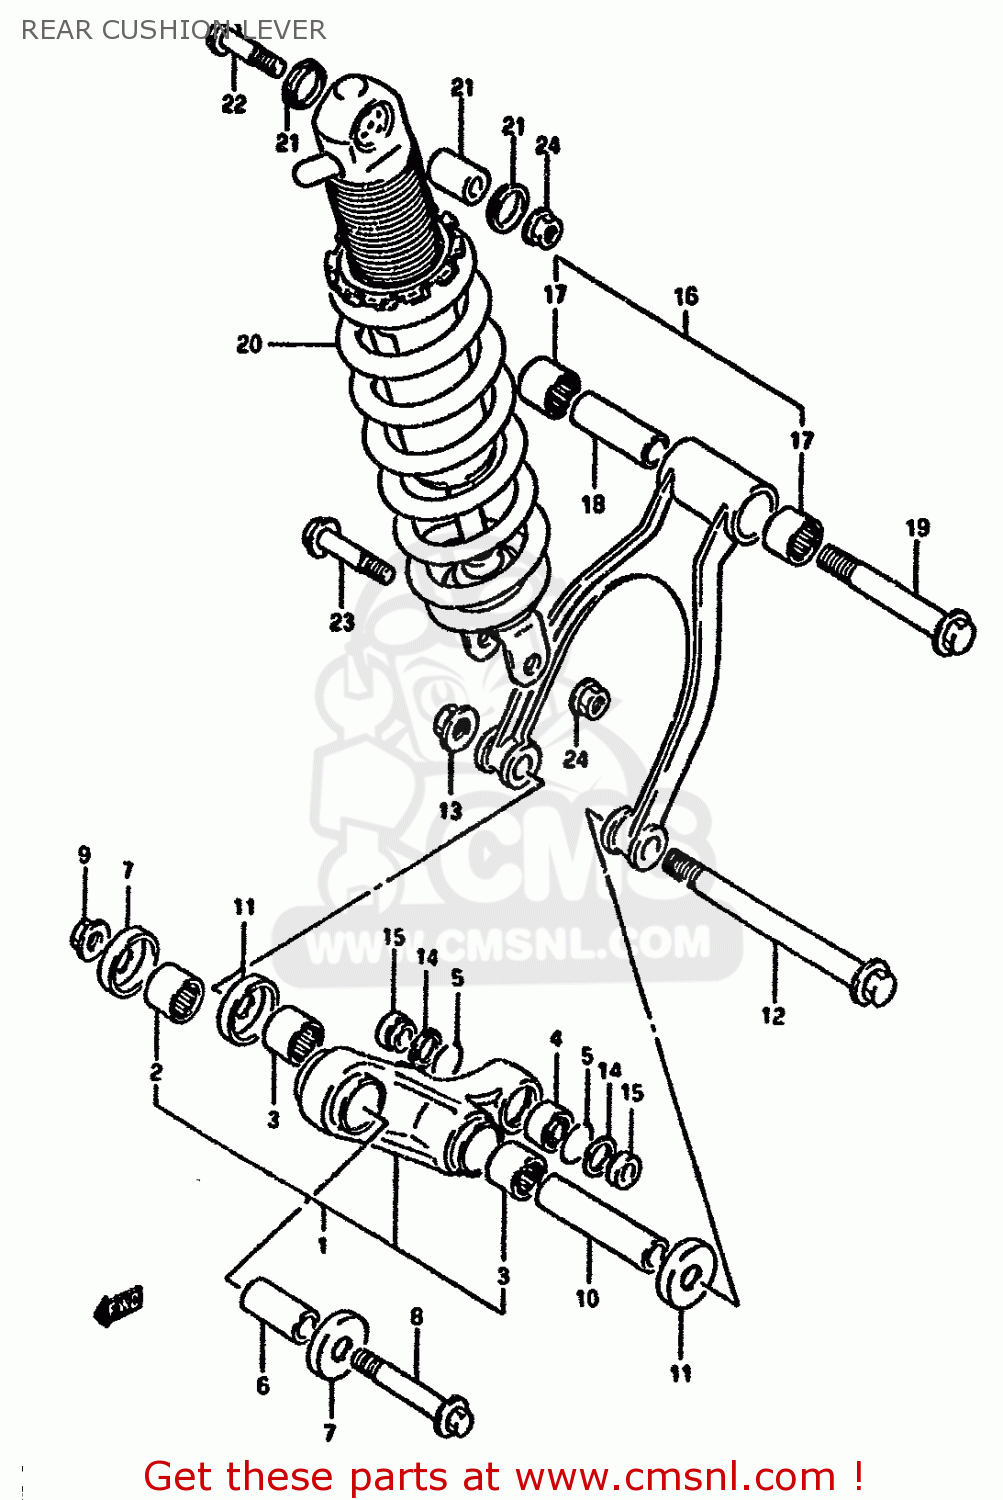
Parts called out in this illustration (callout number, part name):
1	LEVER SET,REAR CUSHION
2	BEARING(20X27X30)
3	BEARING(20X27X23.5)
4	BEARING,REAR SHOCK ABSORBER
5	RING,STOPPER
6	SPACER,RR CUSHION LEVER FR
7	SEAL,RR CUSHION LEVER FR DUST
8	BOLT,RR CUSHION LEVER FR
9	NUT 12MM
10	SPACER (14X20X78)
11	SEAL,RR CUSHION LEVER CTR DUST
12	BOLT,RR CUSHION ROD LWR
13	NUT
14	SEAL,DUST RR SHOCK ABSORBER
15	COLLAR
16	ROD SET,REAR CUSHION,LEFT
17	BEARING(20X27X23.5)
18	SPACER (14X20X63)
19	BOLT,RR CUSHION ROD UPR
20	ABSORBER ASSEMBLY,REAR SHOCK
21	COLLAR
22	BOLT(10X50)
23	BOLT(10X52)
24	NUT
